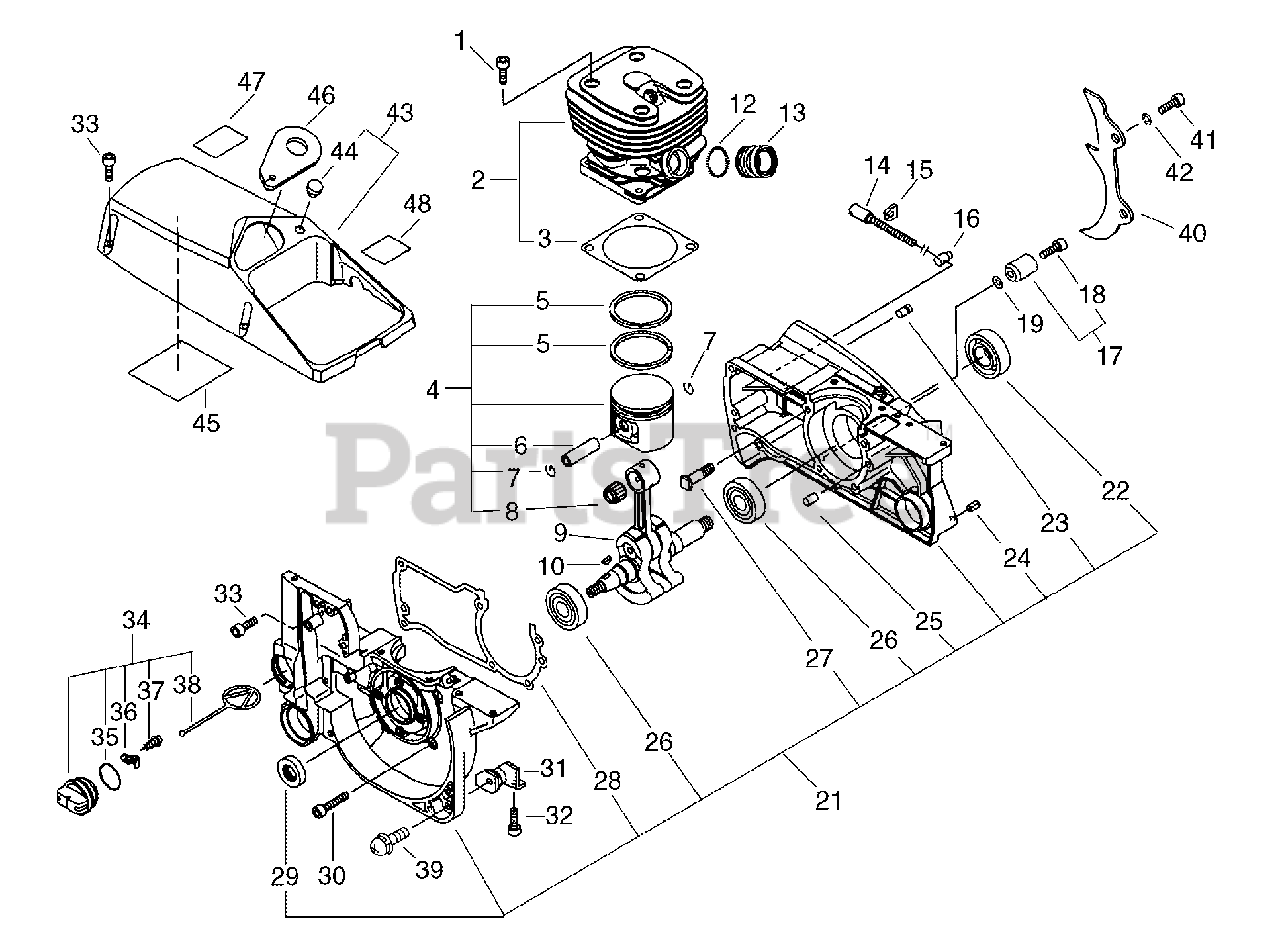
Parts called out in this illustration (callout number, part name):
1	SCREW - 6X25
2	CYLINDER ASSY
3	GASKET, CYLINDER
4	PISTON KIT
5	RING, PISTON
6	PIN, PISTON
7	RING, RETAINING
8	BEARING, NEEDLE
9	CRANKSHAFT ASSY
13	ADAPTOR, INTAKE
14	SCREW, TENSIONER
16	TENSIONER, CHAIN
17	CHAIN CATCHER KIT
18	SCREW - 5X20
19	WASHER - 5
21	CRANKCASE KIT
22	SEAL, OIL
23	VENT, TANK
24	PIN - SPRING -- 5X10
25	PIN - LOCATING
26	BEARING, BALL - 6203
27	STUD, GUIDE BAR
28	GASKET, CRANKCASE
29	SEAL, OIL
30	SCREW - 5X35
32	SCREW - 5X14
33	SCREW - 5X20
34	CAP ASSY
35	O-RING - 25
36	RETAINER
37	SCREW - 3X8
38	CONNECTOR, CAP
39	SCREW - 5X14
41	SCREW - 6X20
42	LOCKWASHER - 6
43	COVER, CYLINDER
45	COVER, ENGINE
46	PLATE, GUIDE
47	LABEL - CAUTION
48	LABEL - CAUTION
